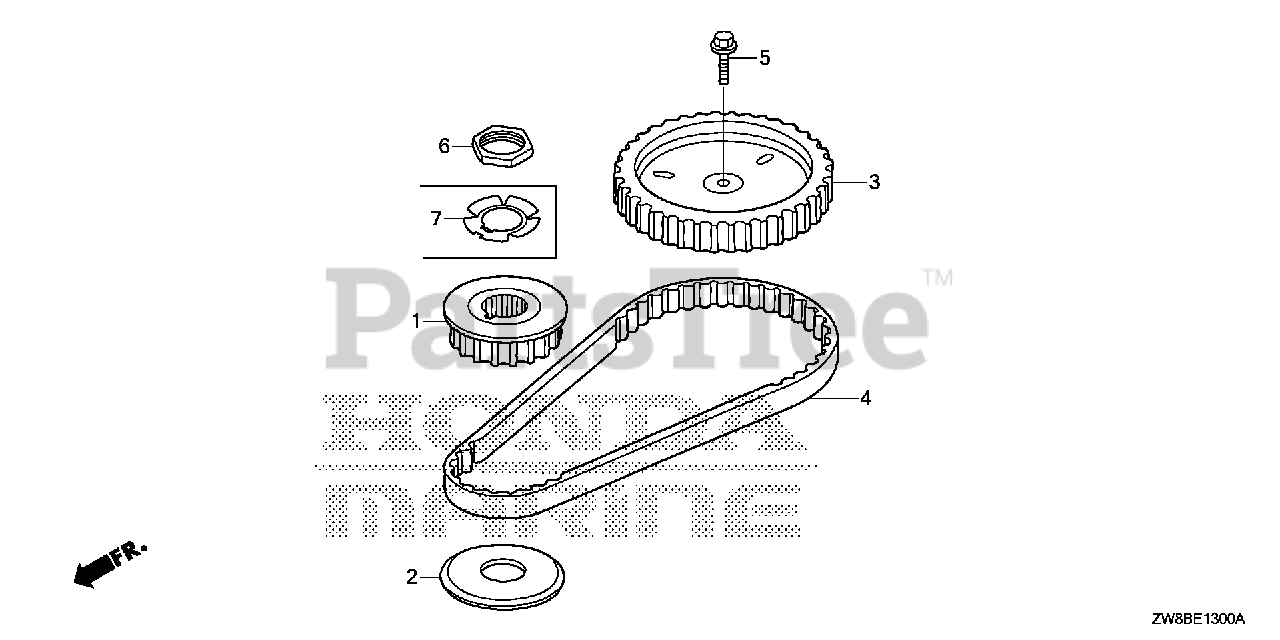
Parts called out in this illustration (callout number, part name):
1	PULLEY, TIMING
2	FLANGE, TIMING PULLEY
3	PULLEY, CAMSHAFT
4	BELT, TIMING (63RU13 B-333)
5	BOLT, FLANGE (6X20)
6	NUT, LOCK (24MM)
7	WASHER, LOCK (24MM)
